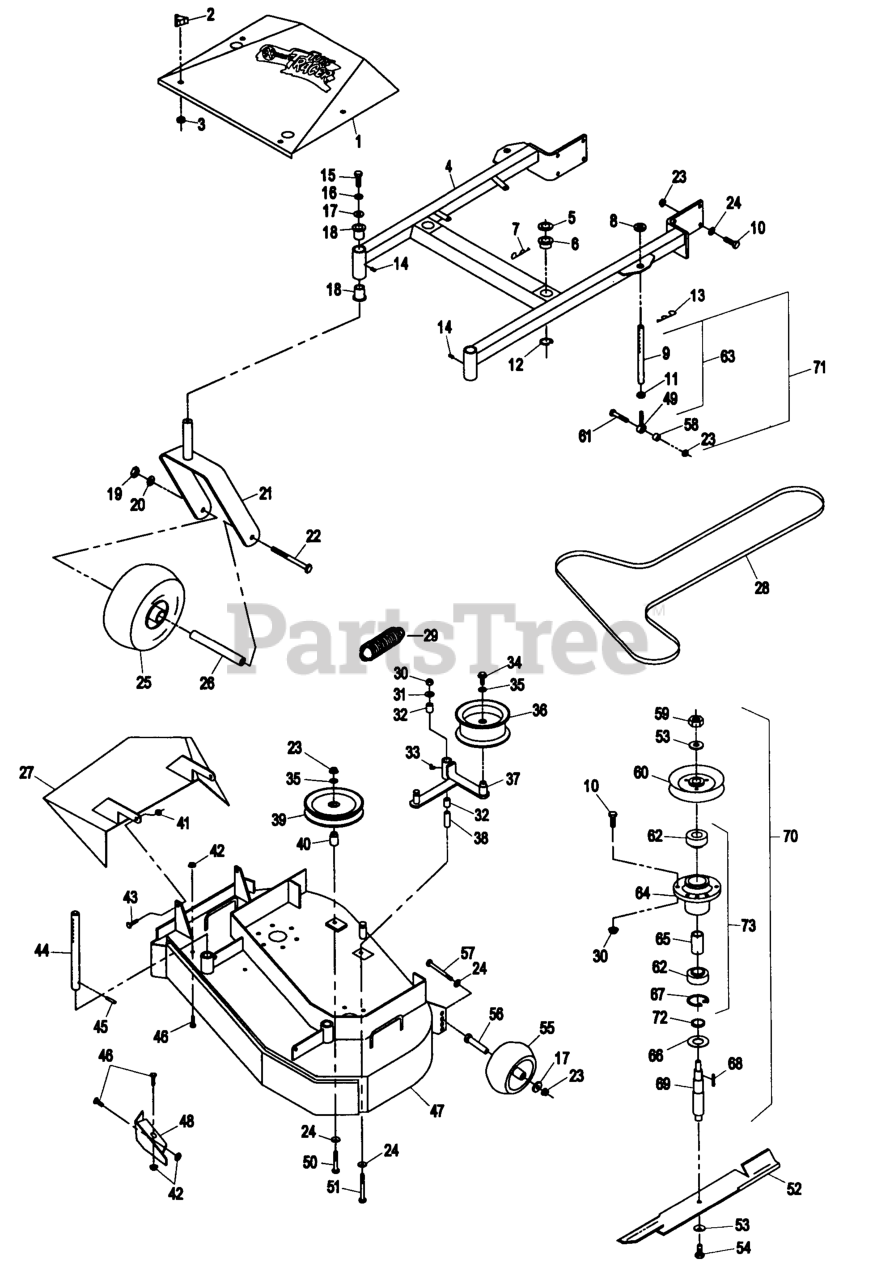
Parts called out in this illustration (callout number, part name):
2	KNOB-3 PRONG
4	DECK SUPPORT W/BSHGS 36"
5	SPACER-DECK SUPPORT
6	BUSHING-DECK
9	LINK, DECK SUPPORT
13	PIN,HAIR COTTER
18	BEARING-FLANGED
28	BELT,DECK DRIVE
32	SLEEVE-BEARING
38	BUSHING-PIVOT, IDLER
39	PULLEY-IDLER
40	BUSHING-IDLER
44	ROD,DECK SUPPORT
47	ASM,DECK W/DECALS TTHP/MH
49	BALLJOINT
51	SCREW-HH
53	WASHER-SPRING
55	ROLLER-SCALP, ANTI
56	BUSHING-ROLLER
60	SHEAVE,W/HUB 5.72
62	BEARING
65	SPACER-BEARING
66	GUARD-BEARING, BOTTOM
68	KEY-RECTANGLE
69	SHAFT,SPINDLE
70	HOUSING,CUTTER COMPLETE
72	SPACER-PULLEY/BEARING
